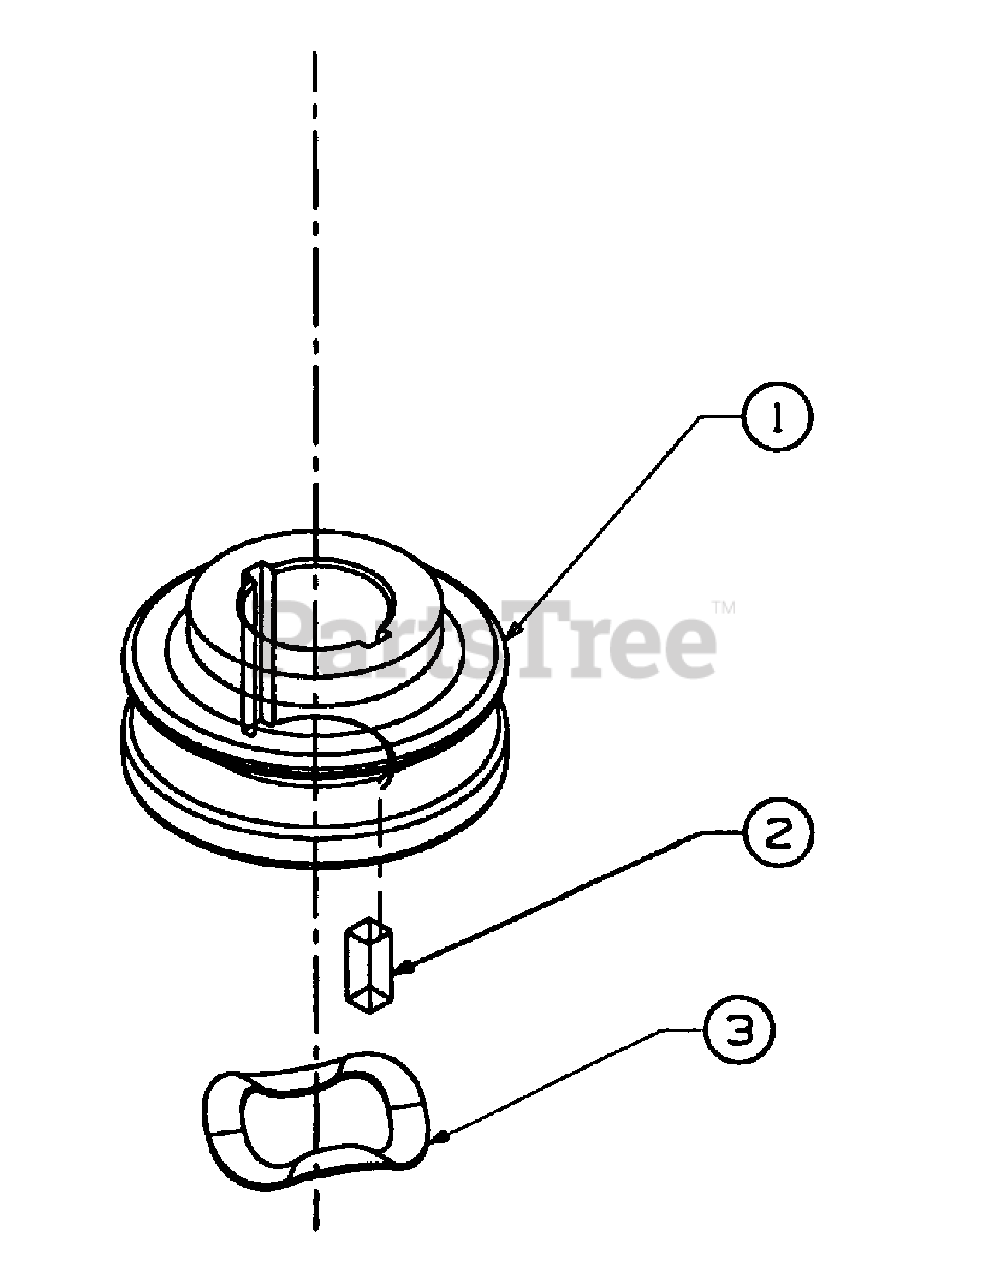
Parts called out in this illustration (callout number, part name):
1	Pulley, Engine
2	Key, Square 3/16
3	Wave Washer
